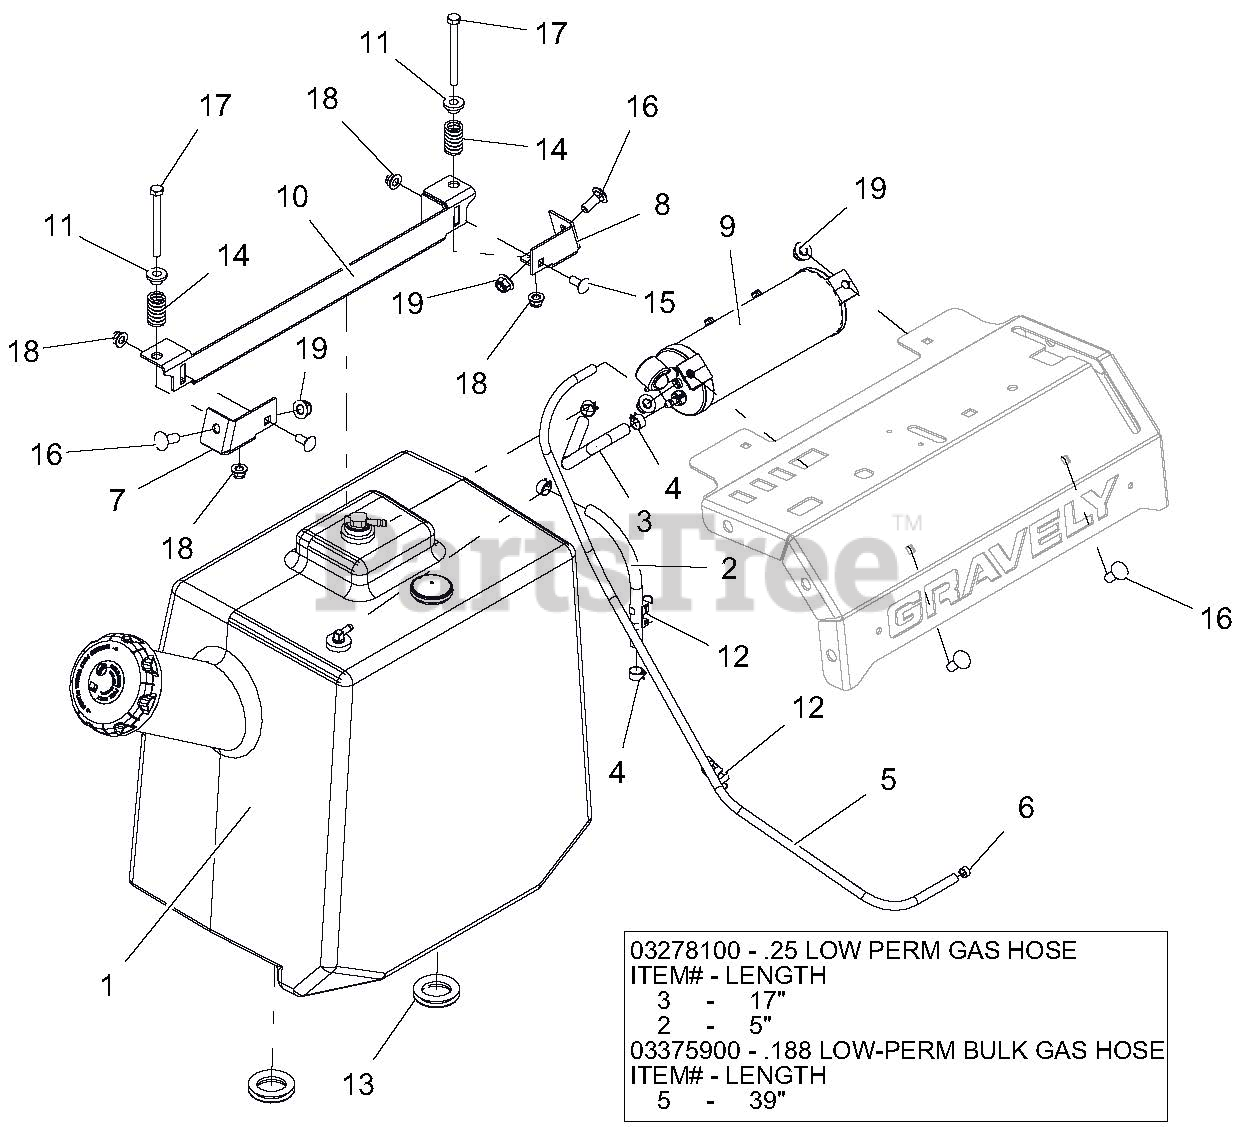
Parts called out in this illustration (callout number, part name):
1	ASSY, EPA PROSTANCE FUEL TANK
2	.25 LOW PERM GAS HOSE
3	.25 LOW PERM GAS HOSE
4	CLAMP, FUEL LINE
5	HOSE, .188 LOW-PERM BULK GAS
6	CLAMP - HOSE, SPRING .188
7	WLDMT, TANK HOLDDOWN-RH
8	WLDMT, TANK HOLDDOWN-LH
9	CANISTER, CARBON 9.3 GAL
10	HOLDDOWN, FUEL TANK
11	BSHG, FLG .385 X .500 X .875 X .406
12	CLIP, T, .38-.50
13	GROMMET, 1.25"
14	SPRG, COMPRESSION
15	BLT-RDHDSQNK .31-18X.75 G5 YWZC
16	BLT-RDHDSQNK .38-16X1.00 G5 YWZC
17	BLT-HEX .31-18X3.25 GR5 YWZC
18	NUT-LK-NYL-FLG .31-18 YWZC
19	NUT-LK-NYL-FLG .38-16 YWZC
